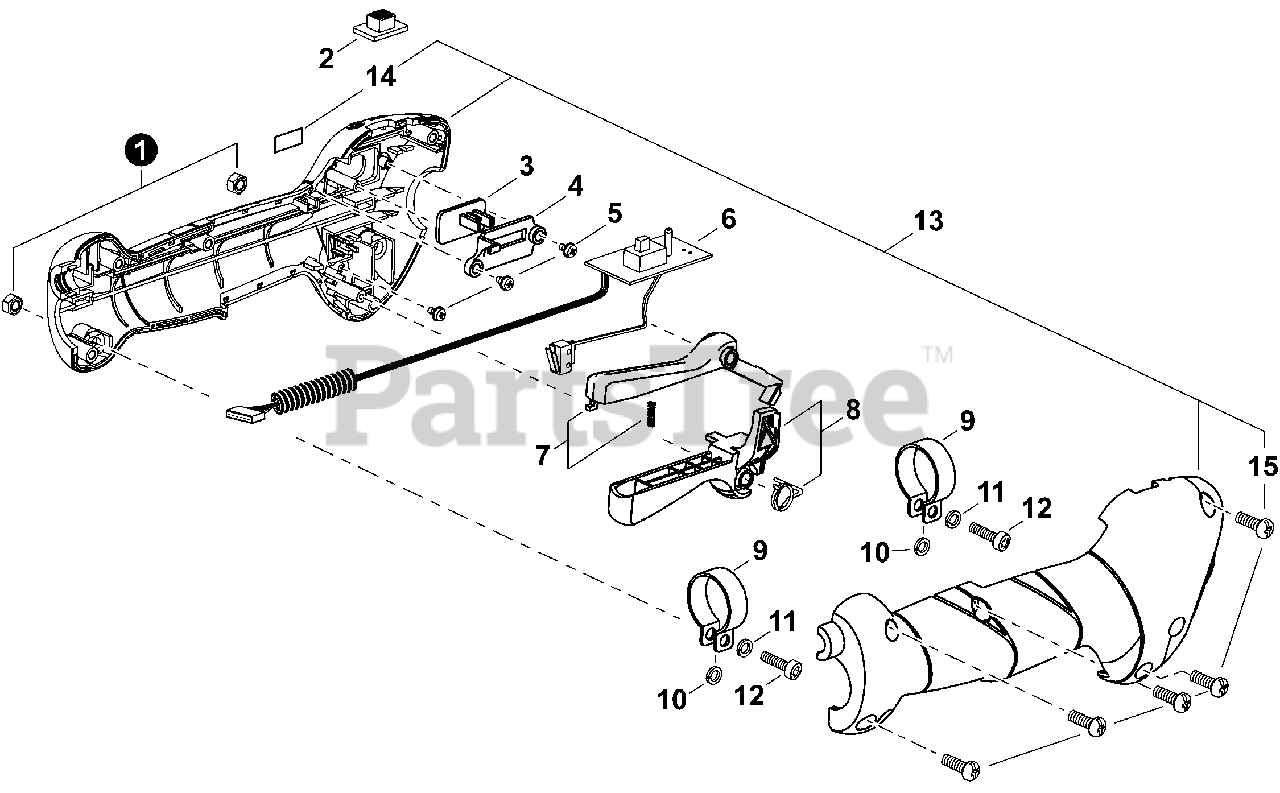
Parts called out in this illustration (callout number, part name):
2	KNOB, SWITCH
3	SWITCH, SPEED CONTROL
4	BRACKET, SWITCH
6	SWITCH, ON-OFF
7	LOCKOUT, THROTTLE
8	TRIGGER, THROTTLE
11	WASHER, SPRING
13	GRIP SET, THROTTLE
14	LABEL, SPEED CONTROL
